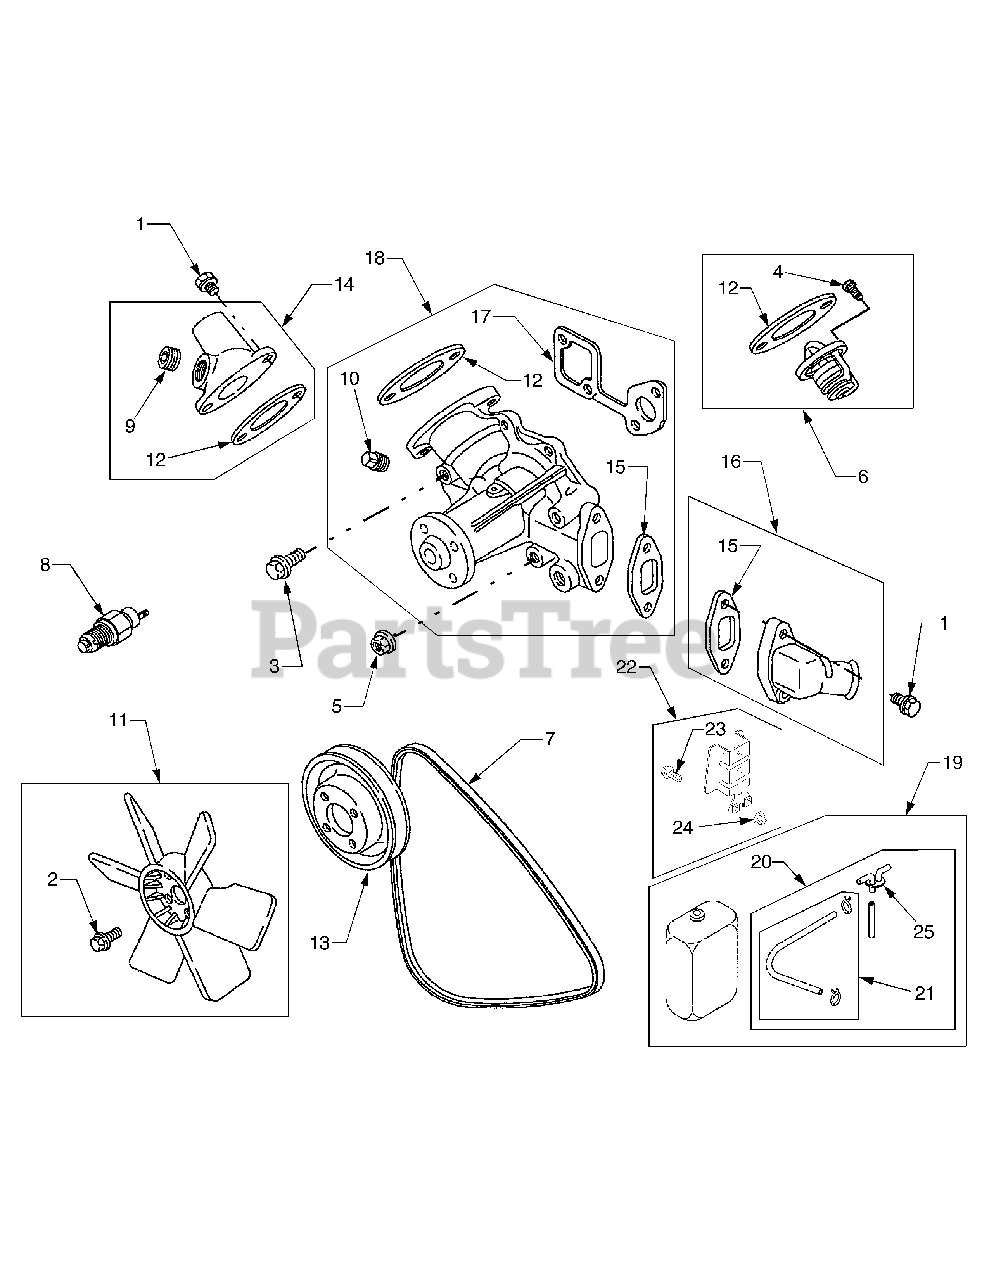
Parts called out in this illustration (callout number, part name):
1	Screw, Hex, 6mm
2	Screw, Hex,
3	Screw, Hex, 8mm
4	Screw, Metric
5	Nut, Hex Metric
6	Thermostat
7	Belt, V
8	Switch, Coolant Temperature
11	Fan, Radiator
12	Gasket, Outlet
13	Pulley, Pump
14	Housing, Outlet
15	Gasket, Inlet Housing
16	Housing, Inlet
17	Gasket, Water Pump
18	Pump, Water
19	Tank, Reserve
20	Cap, Reserve Tank
21	Clamp/Hose Assembly
22	Bracket, Reserve Tank Mtg.
23	Screw, Mtg. Bracket
24	Nut, Mtg. Bracket
25	Cap-Surge Tank
